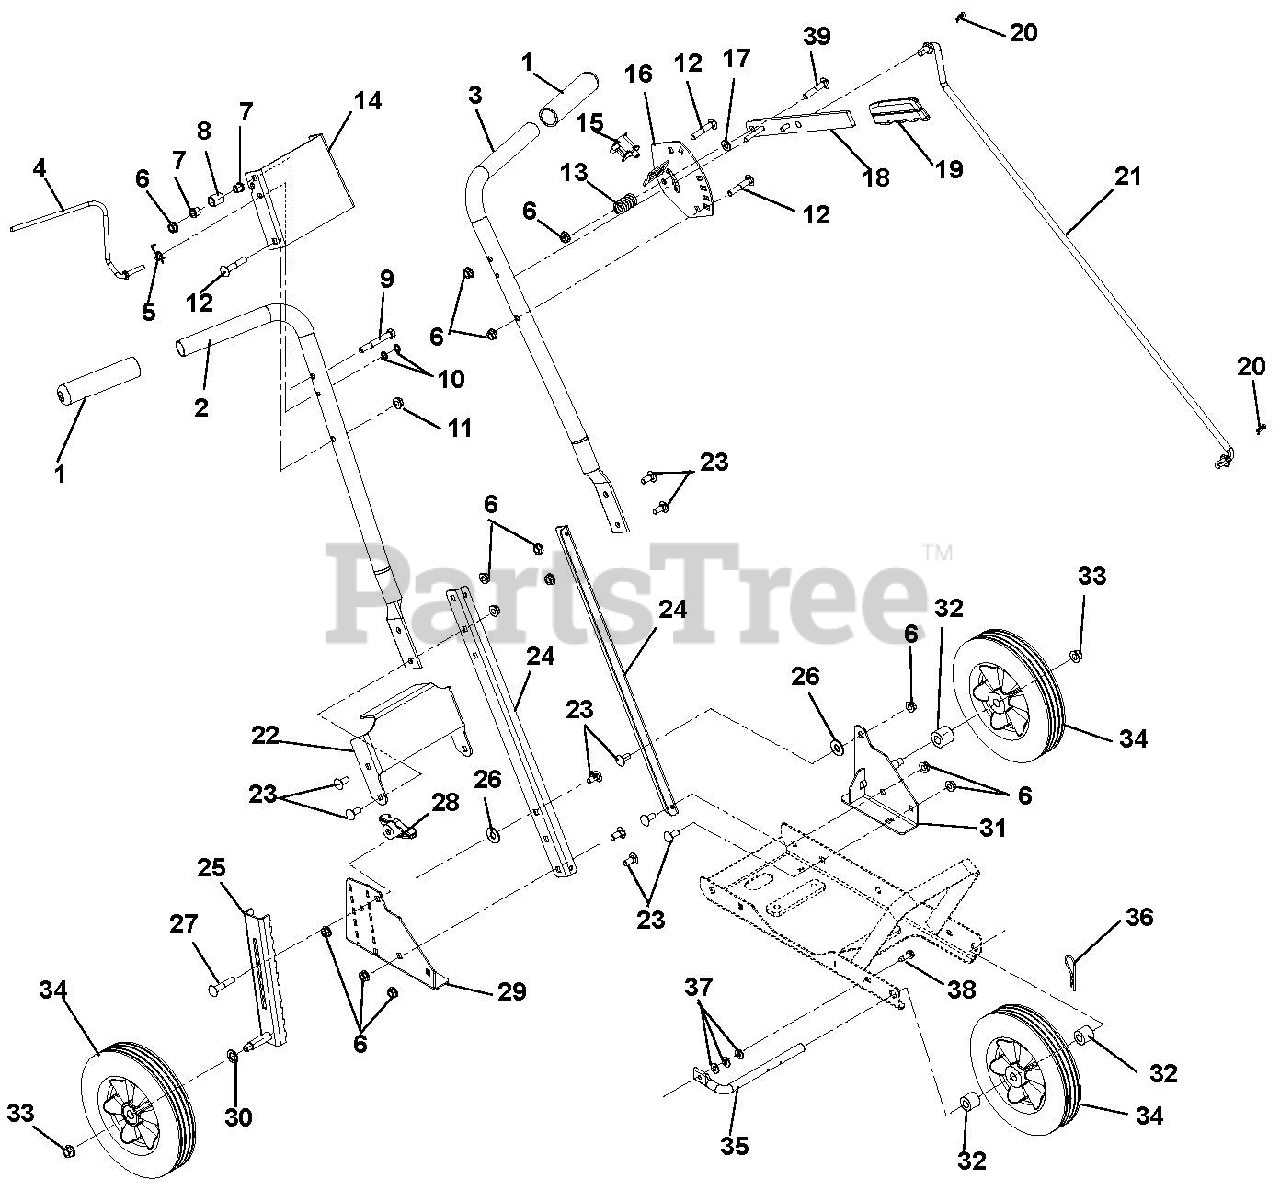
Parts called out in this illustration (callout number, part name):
1	HANDLE GRIP
2	HANDLEBAR,UPPER RH
3	HANDLEBAR,UPPER LH
4	ROD, OPC
5	SPRING, TORSION
6	@NUT-LK-TOP-FLG .31-18 YWZC
7	BSHG-FLG .325X.444X.440X.560
8	SPACER, GROUND .462X.625X.750
9	@BLT-HEX .31-18X2.50 GR5 YWZC
10	RG-RTNG-EXT .250X.010
11	@NUT-LK-TOP-FLG .31-18 YWZC
12	@BLT-RDHDSQNK .31-18X1.75 G5YZ
13	SG-COMP .125X.781X1.250
14	PANEL,UPPER
15	SWITCH- SNAP MTG N.C.
16	DETENT,PIVOT
17	@WSHR-FL-STL.344X.688X.065YWZC
18	LEVER,PIVOT
19	GRIP, PARKING BRAKE (YELLOW)
20	PIN-HAIR, ENDRIES #25 YWZC
21	ROD, PIVOT
22	PANEL,LOWER
23	@BLT-RDHDSQNK .31-18X.75 G5YZ
25	LEG, DROP WHEEL
26	@WSHR-FL-STL.438X1.00X.083 YWZ
27	@BLT-RDHDSQNK .31-18X1.75 G5YZ
28	KNOB,WING .31-18 UNC NYL/TALC
29	BKT,RH WHEEL SUPPORT
29	BKT, RH WHEEL SUPPORT
30	WSHR-FL-STL .52X.827X.062 YWZC
31	BKT,LH WHEEL SUPPORT
32	SPACER .516X1.000X.875
33	@NUT-LK-TOP-FLG .38-16 YWZC
34	WHEEL, PLASTIC-8"X1.75" .50BRG
35	AXLE, FRONT
36	HAIRPIN, #7 CLIP .094X2.31 YWZ
37	@WSHR-FL-STL.281X.62X.065 YWZC
38	SCR-TAP .25-20X.75 HWH TR YWZ
39	@BLT-RDHDSQNK .31-18X2.25 G5YZ
